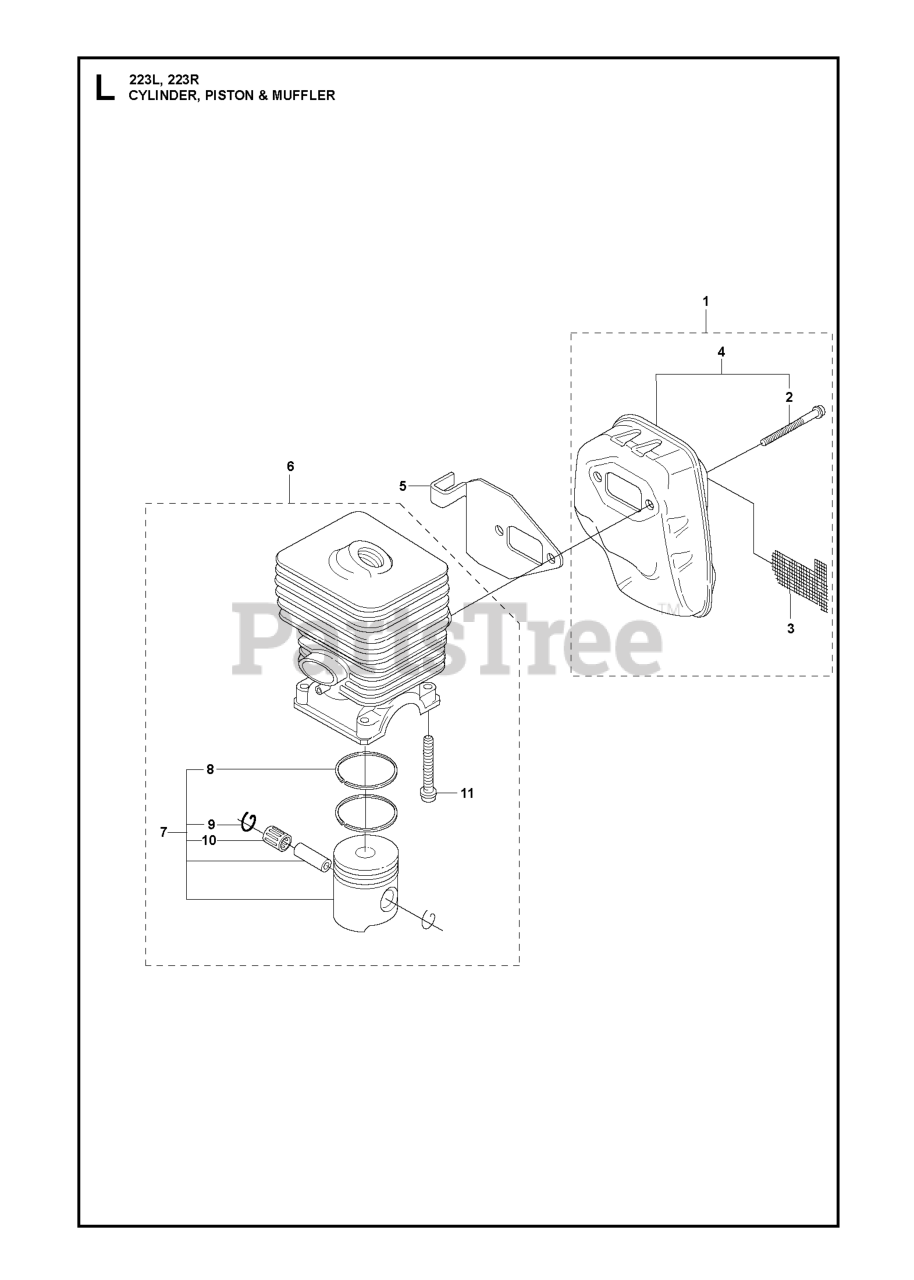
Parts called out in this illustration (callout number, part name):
1	MUFFLER GR 50
3	SCREEN
4	MUFFLER
7	PISTON
8	PISTON RING
11	SCREW MC6S 5X35
